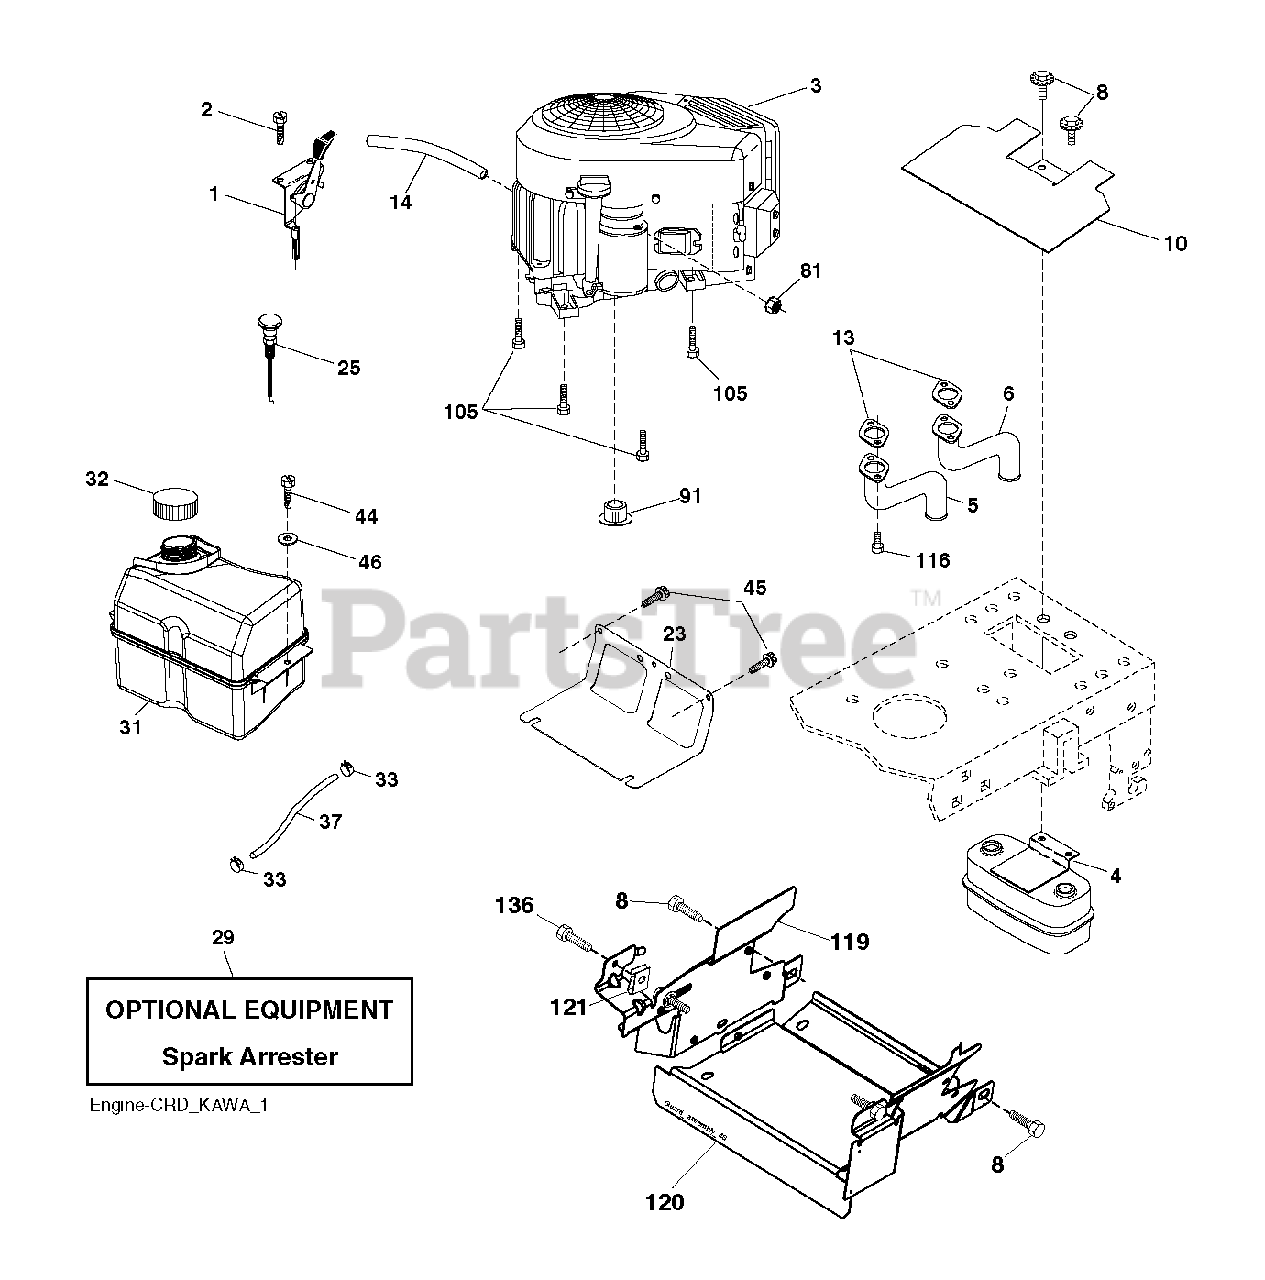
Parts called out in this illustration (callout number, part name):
1	THROTTLE CONTROL
2	SCREW
4	MUFFLER.TWIN.CYL.LOW.TONE
5	TUBE.EXHAUST.LH.FR961/FR730
6	TUBE.EXHAUST.RH.FR961/FR730
8	BOLT, 5/16-18 X 1 3/4
10	SHIELD.HEAT.MUFFLER
14	TUBE, DRAIN OIL ASM.
23	SHIELD.BROWNING.DBR.GUARD
25	CONTROL, CHOKE, 37", PUSH
29	KIT.SPARK ARRESTOR 794945 B&S
31	TANK.ASM.FRNT.DAPCO.E10
32	CAP ASM.FUEL.2.25"FR.
33	HOSE CLAMP
37	LINE.FUEL.20
44	SCREW HEXWSHR 1/4-20X3/4
45	SCREW, 3/8-16X3/4
81	NUT
91	BUSHING.1.375OD
105	SCREW 3/8-16X1
116	NUT.HEX.FLANGE.TOPLOCK
119	LENKRAD
120	GUARD 532199767
136	SCREW.1/4-20X5/8
